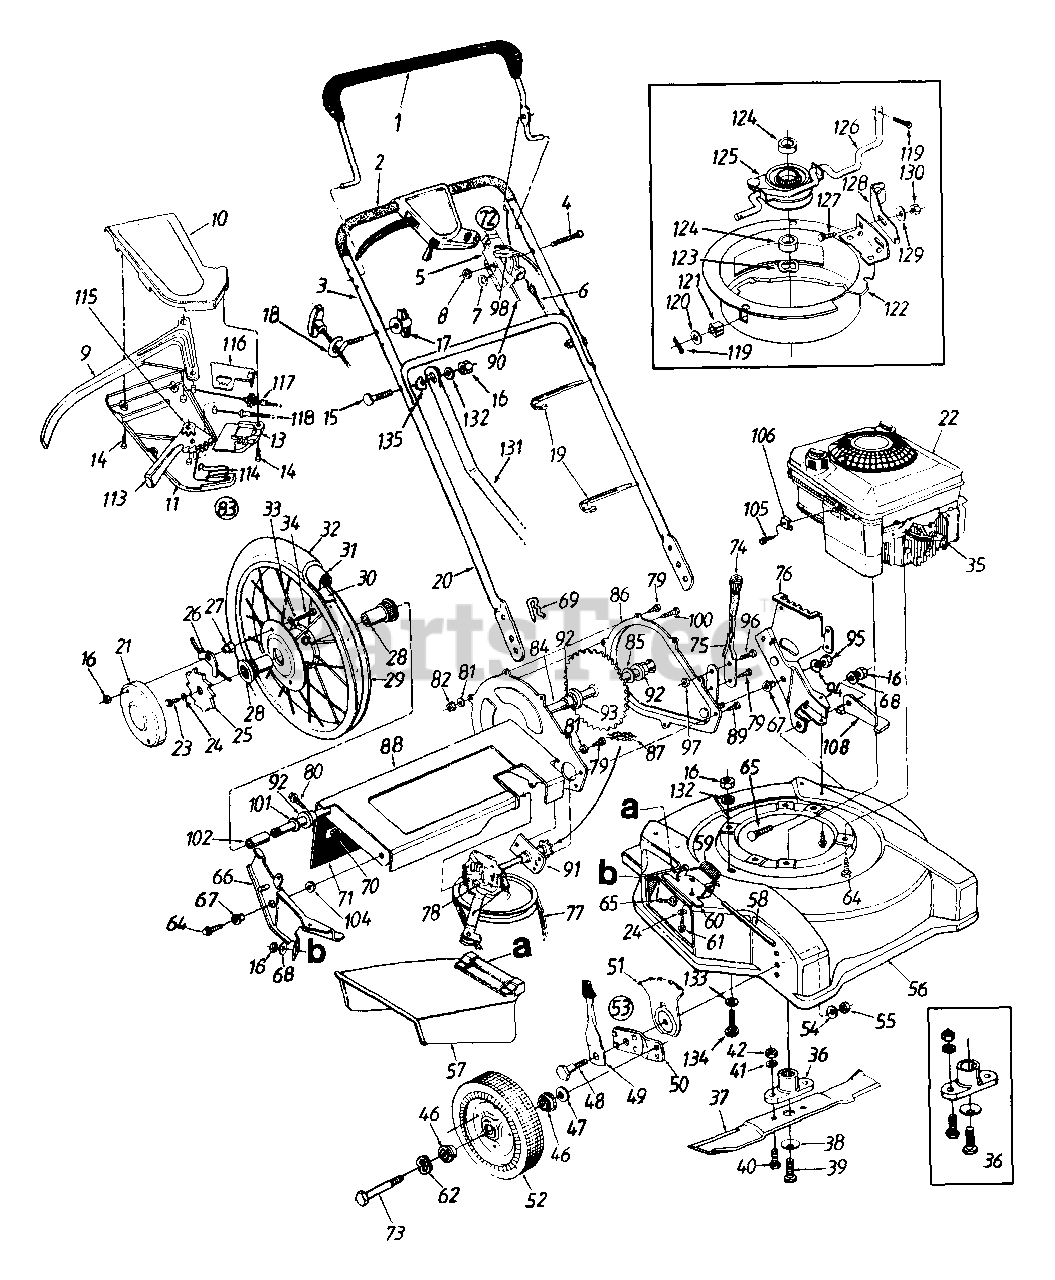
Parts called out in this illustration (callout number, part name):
1	Control Handle Ass'y.
2	Foam Grip
3	Upper Handle
4	Oval C-Sunk Scr.
5	Throttle Body
6	Control Cable - 40.5" Lg.
7	Spring Wash..66" I.D.
8	Hex L-Nut 1/4-20 Thd.
9	Control Lever
10	Control Cover Half - Upper
11	Control Cover Half - Lower
13	Cable Mounting Cap
14	Fl-"C" Sunk Hd. Tap Scr. #10 x .75" Lg.
15	Curved Hd. Bolt 5/16-18 x 2" Lg.
16	Hex Nut 5/16-18 Thd.
17	Handle Knob 1/4-20 Thd.
18	Rope Guide
19	Cable Tie
20	Lower Handle
21	Wheel Cover
22	Engine
23	Hex Bolt 1/4-20 x .75" Lg. (Gr. 5)
24	Bell-Wash. 1/4" I.D.
25	Wheel Ratchet
26	Pawl and Spring Ass'y.
27	Special Hex Nut 5/16-18 Thd.
28	Flange Bearing .63" I.D.
29	Rim Ass'y. Only 16" x 2.1"
30	Rimstrip 16" x 7/8"
31	Inner Tube 16" x 2.12"
32	Chevron Tire 16" x 2.125"
33	Intern. L-Wash. 5/16" I.D.
34	Hex Bolt 5/16-18 x 1.0" (Gr. 5)
35	Spark Plug Boot
36	Blade Adapter Kit
37	22" Blade
38	Bell-Wash..39" I.D.
39	Hex Bolt 3/8-24 x 1.5" Lg.
40	Hex Bolt 3/8-24 x 1" Lg.
41	L-Wash. 3/8" I.D.
42	Hex Nut 3/8-24 Thd.
46	Ball Bearing 1/2" I.D.
47	Bell-Wash..38" I.D.
48	Shld. Bolt .5"
49	Spring Lever Ass'y. w/Knob
51	Height Adj. Plate
52	Wheel Ass'y. Comp.
53	Height Adj. Ass'y. Comp. - R.H.
54	Bell-Wash..39" I.D. x 1.38"
55	Hex Nut 3/8-16 Thd.
58	Hinge Pin
59	Torsion Spring
60	Adapter Plate
61	Hex TT-Tap Scr. 1/4-20 x .5"
62	Wave Wash..51" I.D. x .78"
64	Hex TT-Tap Scr. 3/8-16 x 1"
65	Carriage Bolt 5/16-18 x .62" Lg.
66	Handle Brkt. Ass'y. - R.H.
67	Shld. Spacer .5" x .10"
68	Bell-Wash. 5/16" I.D.
69	Intern. Cotter Pin 5/16" Dia.
70	Retaining Strip
71	Rear Flap
72	Throttle Box Comp.
73	Front Axle Bolt
75	Height Adjustment Lever
78	Transmission Comp.
79	Hex B-Tap Scr. 1/4 x .38" Lg.
80	Hex AB-Tap Scr. 1/4 x .62" Lg.
81	L-Wash. 1/4" I.D.
82	Hex Nut 1/4-20 Thd.
83	Wheel Ass'y. Comp.
84	Sprocket and Axle Ass'y.
85	Fl-Wash..635" I.D. x 1.0" O.D.
90	Throttle Cable - 61" Lg.
91	Hex Bearing Cup
92	Hex Flange Brg..631" I.D.
93	Spacer .63" I.D. x 1.25"
94	Fl-Wash..385" I.D. x .87" O.D.
95	Hex L-Nut 3/8-24 Thd.
96	Hex Bolt 3/8-16 x .62" Lg.
97	Flanged L-Nut 3/8-16 Thd.
98	Throttle Lever
99	Hex B-Tap Scr. 5/16-18 x .5"
100	Hex Bolt 1/4-20 x .5" Lg.
101	Fl-Wash..632" I.D. x .943"
102	Spacer .628" I.D. x .875"
104	Fl-Wash..38" I.D. x 1" O.D.
105	Wash. Hd. Scr. #10-32 x .62" Lg.
106	Casing Clamp
108	Deck Bracket
113	6-Spd. Shift Lever
114	Shift Lever Spring
115	3-Tooth Rack Gear Insert
116	6-Speed Rack Cable Brkt.
117	S.P. Cable
118	Spd. Control Cable - 50" Lg.
119	Cotter Pin 3/32" Dia.
120	Fl-Wash..33" I.D. x .687" O.D.
121	Flanged Bushing
124	Spacer .885" I.D. x 1" O.D.
125	Pulley Ass'y.
126	Shift Rod
127	Carr. Bolt 1/4-20 x .5" Lg.
128	6-Speed Adj. Cable Brkt.
129	Bell-Wash..265" I.D.
130	Hex L-Nut 1/4-20 Thd.
131	Handle Strut
132	L-Wash. 5/16" I.D.
133	Fl-Wash. 7/16" I.D. x 7/8" O.D.
134	Carriage Bolt 5/16-18 x .62" Lg.
135	Saddle Wash..32" I.D. x .93"
